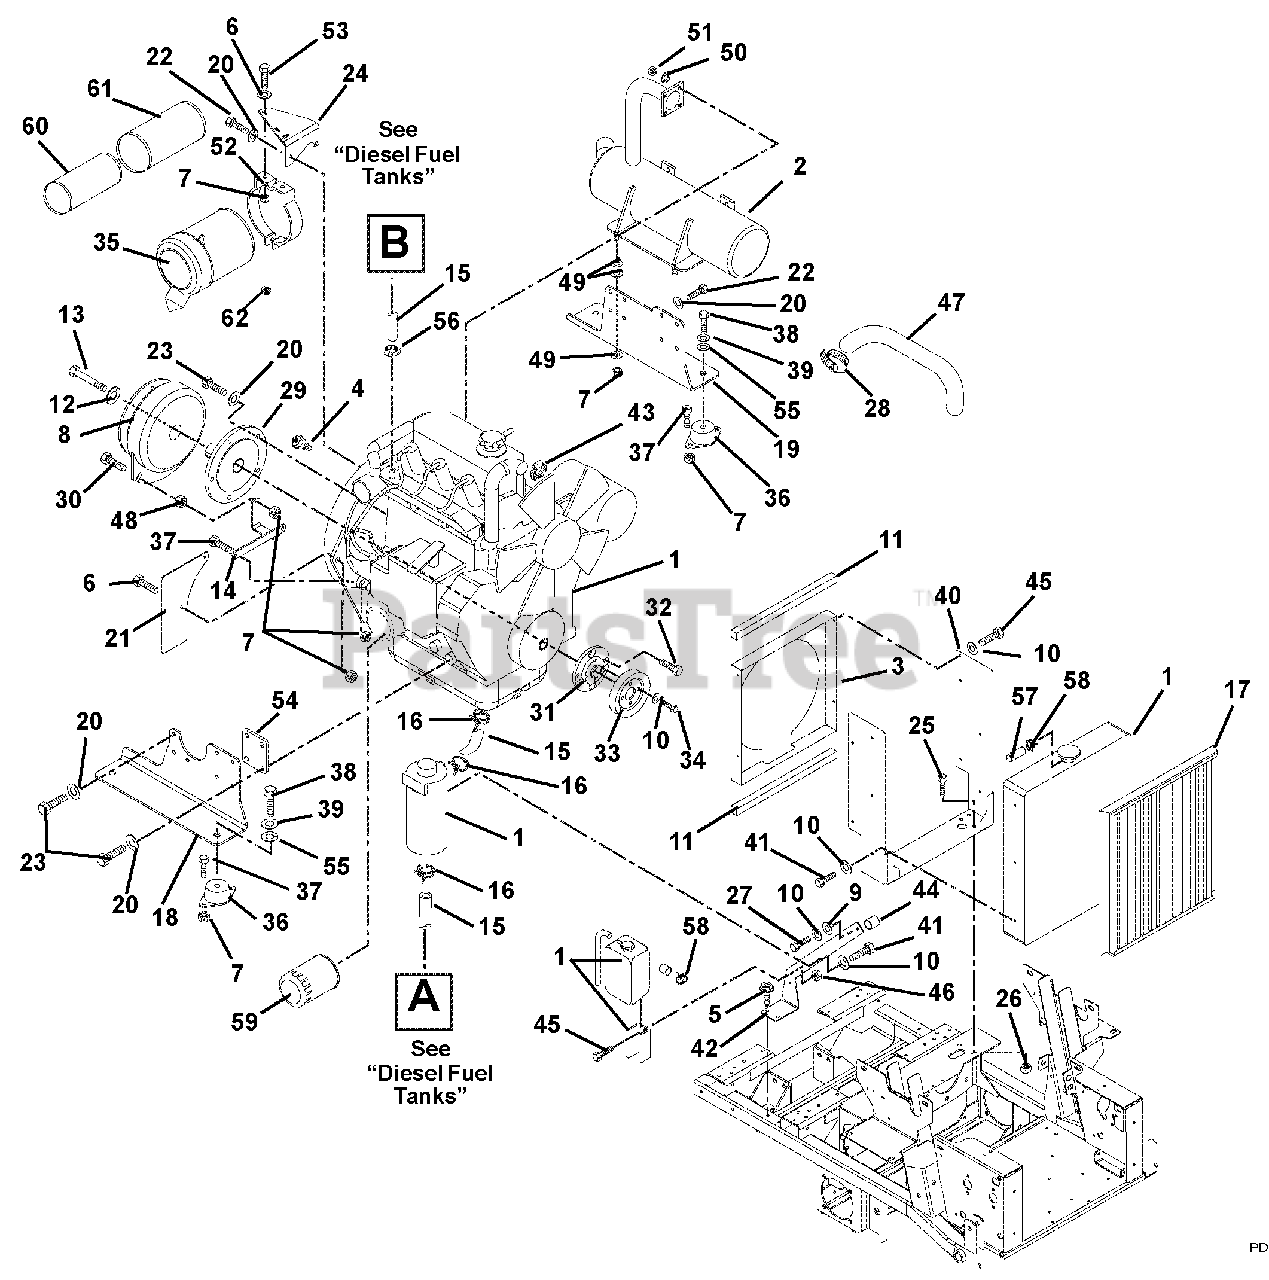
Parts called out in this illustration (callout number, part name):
1	Engine, 27HP Diesel (Daihatsu) (316)
2	Muffler (316)
3	Weldment, Radiator Shroud
4	Sender, Temperature
5	Screw, Tapping .38-16 x .75 Hex Washer Head
6	Bolt, Hex .31-18 x .75 Grade 5
7	Nut, Locking Top Flange .31-18
8	Electric Clutch
9	Washer, Flat Steel .281 x .62 x .065
10	Washer, Locking .25 x .062 Regular
11	Seal, Trim-LOK Bulk .06 Bubble
12	Washer, Locking .44 x .109
13	Bolt, Hex .44-20 x 2.50 Grade 5
14	Stabilizer, Clutch
15	Gas Line, Bulk .31" ID
16	Hose, Clamp
17	Screen, Radiator
18	Mount, Engine Right Hand
19	Mount, Engine Left Hand
20	Washer, Lock .31 x .078 Regular
21	Guard, Flywheel
22	Bolt, Hex M8-1.25 x 20
23	Bolt, Hex M8 x 1.25 x 25 Grade 8
24	Bracket, Air Cleaner
25	Bolt, Hex .38-16 x 1.00 Grade 5
26	Nut, Locking Top Flange .38-16
27	Bolt, Hex M6-1.00 x 45
28	Clamp, 2.50" Dia. Hose
29	Weldment, Stub Shaft (317)
30	Bolt, Hex .31-18 x 1.50 Grade 5
31	Adapter, Sheave
32	Bolt, M8-1.25 x 25
33	Sheave, Poly-V 1.0 x 3.25
34	Bolt, Hex .25-20 x .75 Grade 5
35	Assembly, Air Cleaner
36	Mount, Engine
37	Bolt, Hex .31-18 x 1.00 Grade 5
38	Bolt, Hex .50-20 x 1.00 Grade 5
39	Washer, Locking .50 x .125 Regular
40	Bracket, Radiator Mounting
41	Bolt, Hex M6-1 x 16
42	Bracket, Overflow Mounting
43	Clamp, Hose 1.50 x .81 x 1.42
44	Spacer .328 x .76 x 1.01
45	Bolt, Hex .25-20 x .75 Grade 5
46	Nut, Locking Top Flange .25-20
47	Hose, Air Cleaner (316)
48	Nut, Hex .31-18
49	Washer, Flat Steel .38 x .875 x .083
50	Washer, Locking .31 x .078 Regular
51	Nut, Hex M8-1.25
52	Bracket, Air Cleaner Mount
53	Washer, Flat Steel .38 x .875 x .083
54	Spacer, Engine Mounting
55	Washer, Flat Steel .531 x 1.06 x .095
56	Hose Clamp
57	Gas Line, Bulk .25 I.D.
58	Clamp, Hose Wire .49/.51 x .116
59	Oil Filter
60	Element, Inner Safety
61	Element, Outer Primary
62	Plug, Pipe .125-27
NS	Kit, Break Pole Module Replacement
